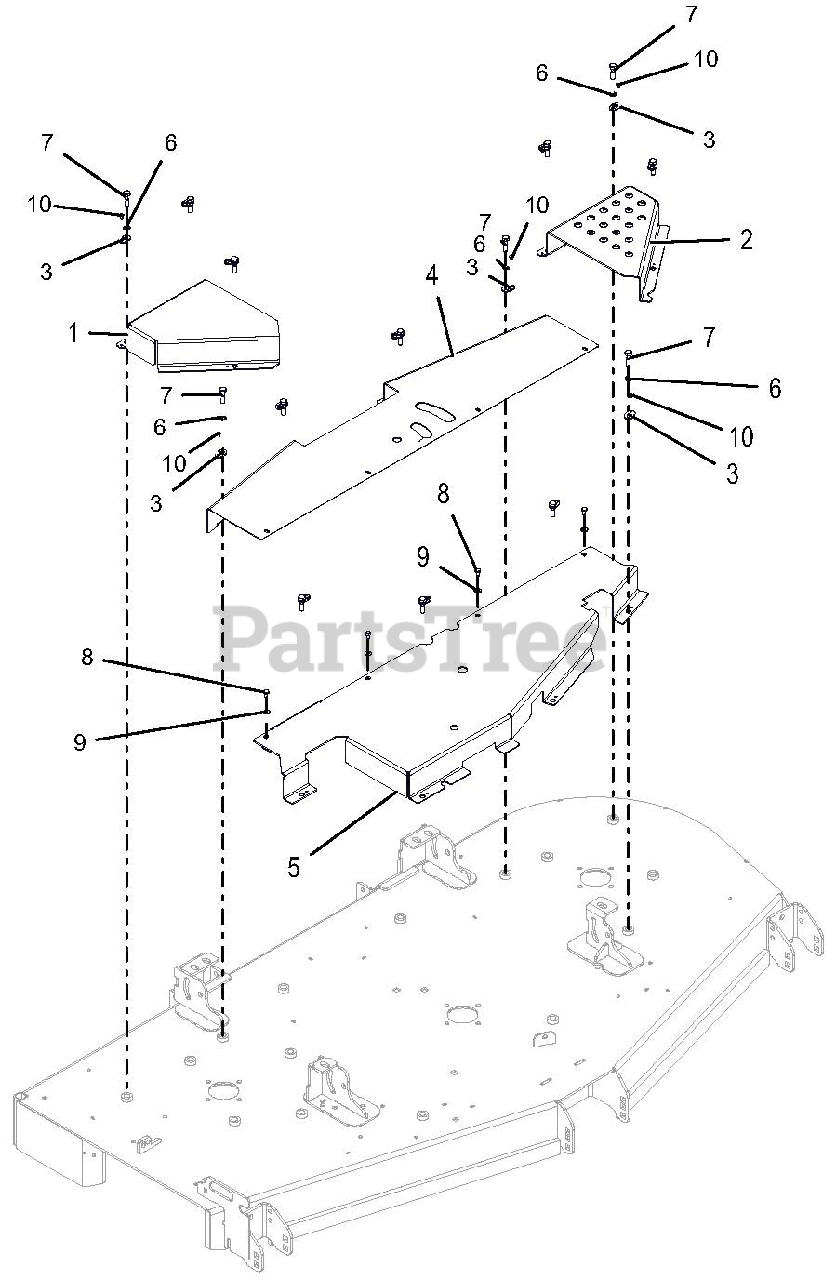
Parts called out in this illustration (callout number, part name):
1	GUARD, RH PT200 CE BELT (BLACK)
2	GUARD, LH PT200 CE BELT (BLACK)
3	KEEPER, BOLT
4	BRKT, BACK BELT GUARD 272-CE (BLACK)
5	WDMT, FRONT BELT GUARD 72"-CE
6	@WSHR-LK-EXT.391X.628X.036YWZC
7	BLT,HEX.38-16X1.25 GR5 CAPTIVE
8	@BLT-HEX .25-20X.50 GR5 YWZC
9	@WSHR-FL-STL.281X.62X.065 YWZC
10	RVT-POP .187x.250 (#64) YWZC
